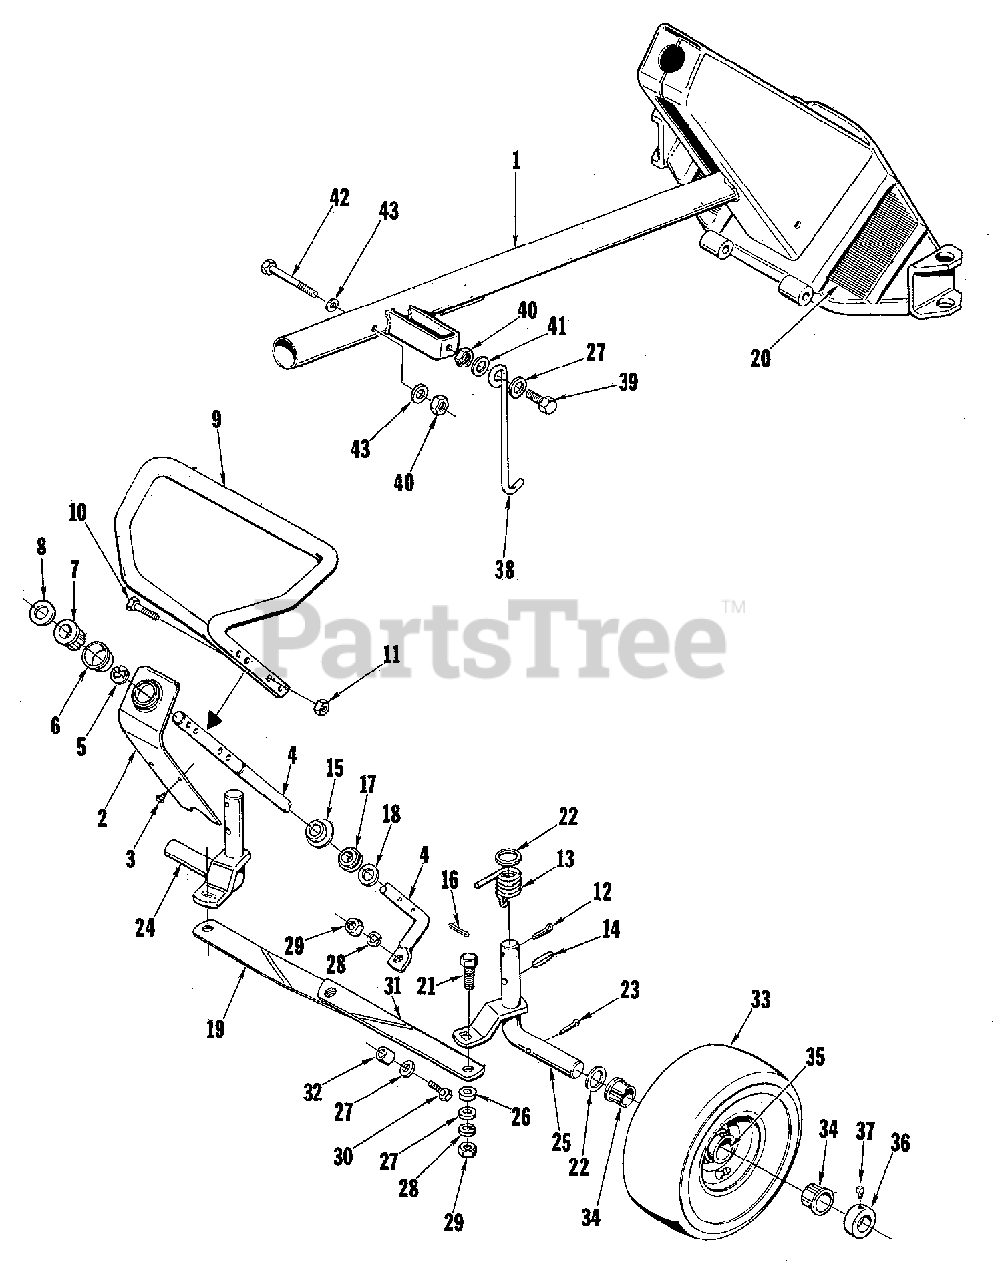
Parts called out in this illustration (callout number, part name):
1	FRAME & AXLE, Front
2	COVER, Steering Support
3	SCREW, Self Tapping, 10 x 3/8
4	SHAFT, Steering
6	CUP, Steering
7	BUSHING, Steering
9	HANDLE, Steering
10	SCREW, Hex Cap, 5/16-18 x 1-1/2
11	NUT, Hex Lock, 5/16-18
12	PIN, Cotter, 5/32 x 1
13	SPRING, Torsion
14	PIN, Roll, 5/16 x 1-1/4
15	CUP, Steering Shaft
16	PIN, Coter, 5/32 x 1-1/4
19	LINKAGE, Steering, L.H.
20	PAD, Foot, Right & Left
21	SCREW, Hex Lock, 3/8-16 x 1
23	PIN, Cotter, 3/16 x 1-1/4
24	SPINDLE, L.H.
25	SPINDLE, R.H.
27	WASHER, Flat, 3/8
28	WASHER, Lock, 3/8
29	NUT, Hex, 3/8-16
30	SCREW, Hex Cap, 3/8-16 x 1-1/2
31	LINKAGE, Steering, R.H.
33	WHEEL & TIRE, Front, 4.1 x 3.5 x 4
34	BEARING RELIEF
37	SCREW, Set, 5/16-18 x 5/16
39	SCREW, Hex Cap, 3/8-16 x 1
40	NUT, Hex Lock, 3/8-16
41	WASHER, Plastic
42	SCREW, Hex Cap, 3/8-16 x 3
43	WASHER, Plain
